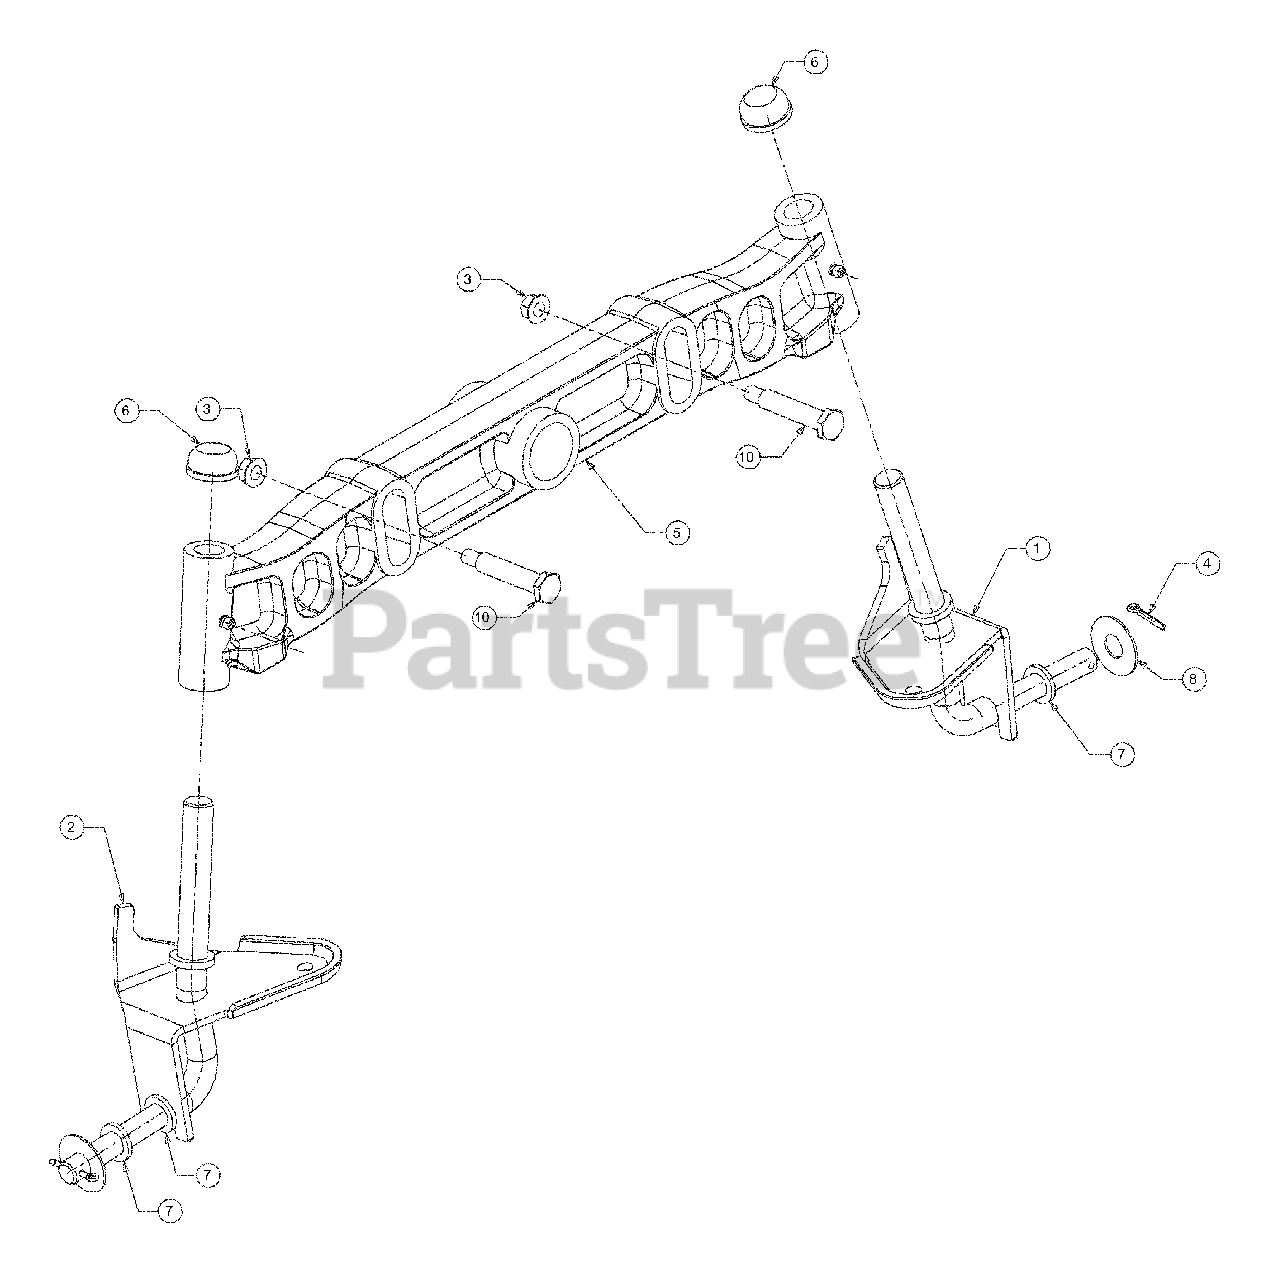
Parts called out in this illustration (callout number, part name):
1	AXLE ASM:LH .750 DIA
2	AXLE ASM:RH .750 DIA
3	NUT:FLGLK:3/8-16:GRF:TOP LK
4	PIN:COT:5/32:1.25
5	AXLE:PIVOT:BAR CAST .750 DIA
6	CAP:PUSH:3/4
7	WASHER:FL .64ID X 1.00OD X .1
8	WASH:FL: .635 X 1.589 X .060
10	SCR:SHLDR:.500 X 2.230:3/8-16
